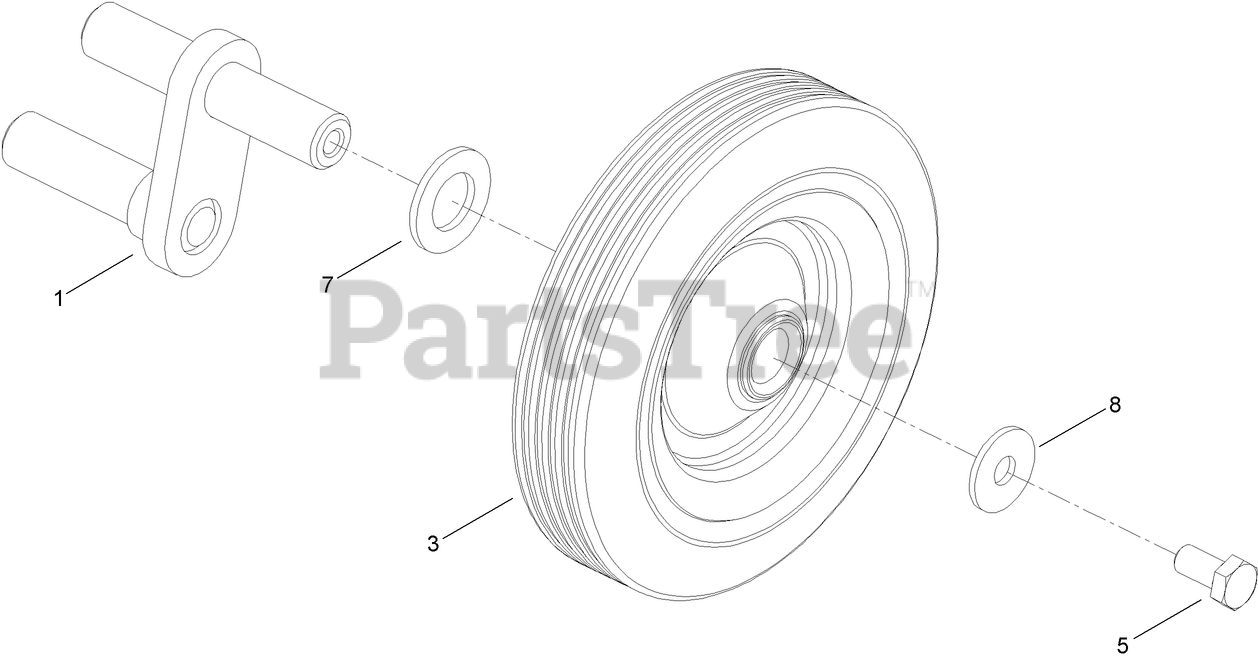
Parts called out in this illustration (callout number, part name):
1	ARM-UNDERCARRIAGE
5	SCREW-HH
7	WASHER
8	WASHER
